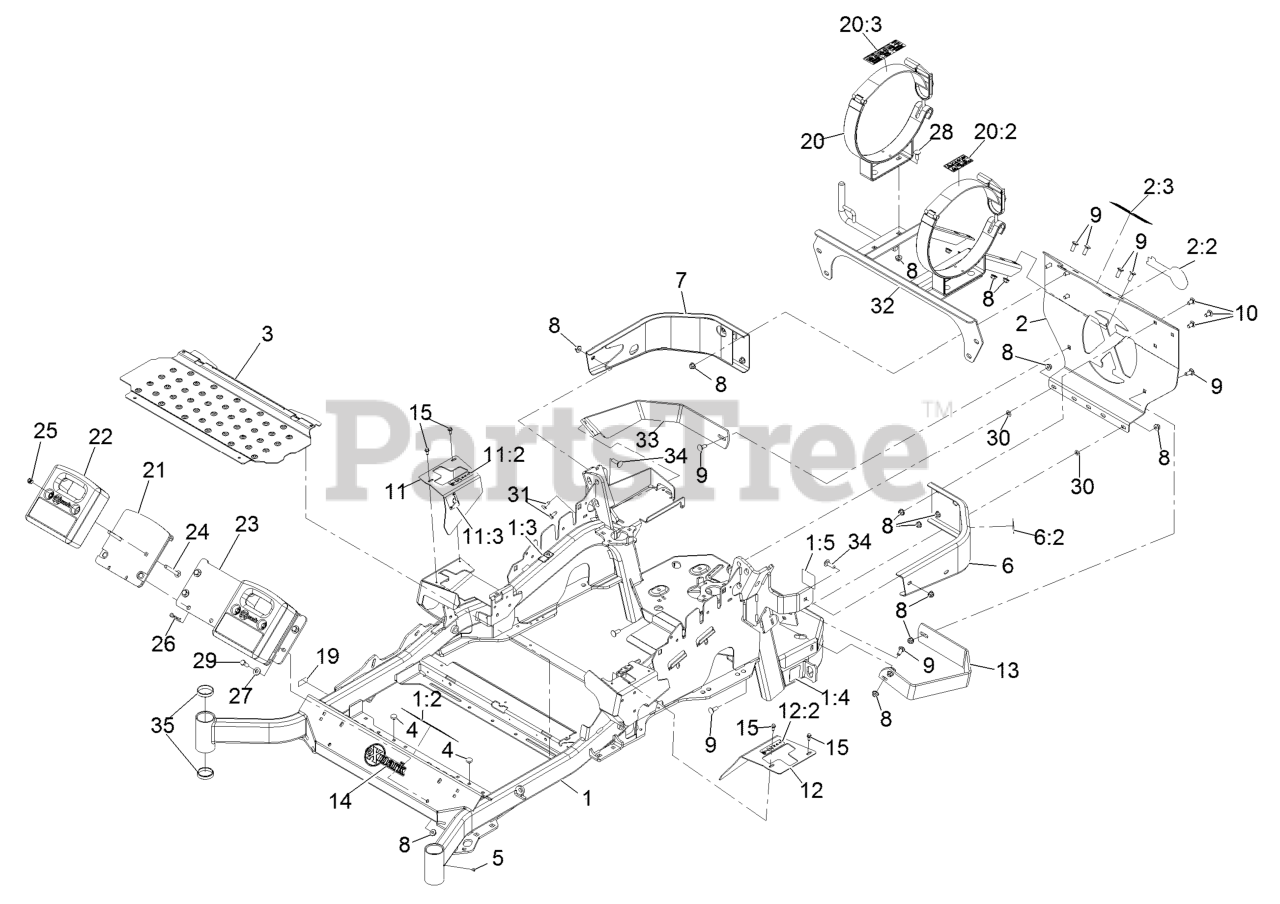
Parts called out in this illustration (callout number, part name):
1:2	DECAL-DANGER
1:3	DECAL-WARNING
1:4	DECAL-HAZARD, PINCHED FINGER
1:5	DECAL-SPARK ARRESTER
2	REAR GUARD-LP W/DECALS
2:2	DECAL-EXMARK LOGO
2:3	Decal-LPG Fuel Tank Replacement
6	LH BUMPER ASM
6:2	DECAL-WARNING
7	BUMPER-RH
8	NUT-HF, NI
9	SCREW-CARR
10	SCREW-CARR
11	RH MOTION CONTROL COVER ASM
11:2	DECAL-CONTROL, MOTION
11:3	DECAL-PARK BRAKE, CE
12	LH MOTION CONTROL COVER ASM
12:2	DECAL-CONTROL, MOTION
13	GUARD-MUFFLER
14	DECAL-EXMARK LOGO
15	SCREW-HWH
19	Decal-Patent Ttco.Com
20	TANK BRACKET ASM (SET)
20:2	Decal-LPG Warning
20:3	Decal-LPG Tank Spec
21	WLD,WEIGHT MOUNT
22	WEIGHT,CAST 36LB
23	PLATE,WEIGHT ASM MOUNT
24	SCREW-CARR
25	NUT-LOCK, NI
26	PIN-HAIR
27	WASHER-BELLEVILLE
28	BOLT-CARR
29	SCREW-HH
30	NUT-PUSH
31	Screw-HWH 5/16-18 X 3/4 Tf
32	SUPPORT-TANK
33	STRAP-GUARD
34	BOLT-CARR
35	CUP-BEARING
